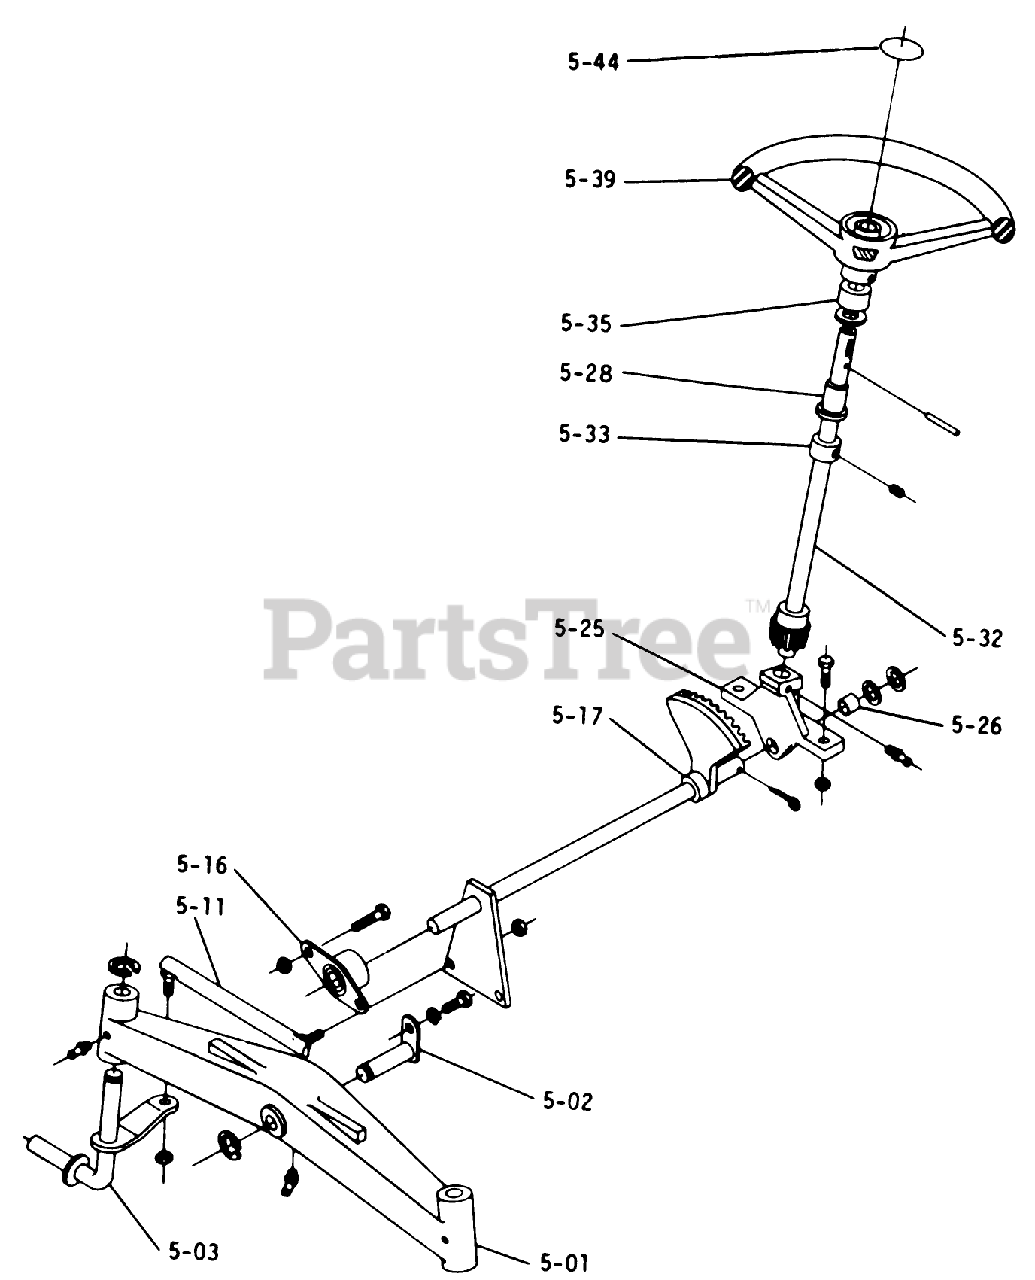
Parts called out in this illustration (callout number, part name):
5-01	FITTING-GREASE
5-02	PIN AND PLATE ASM
5-03	E-RING
5-16	BEARING-FLANGED
5-17	WASHER-SHIM
5-17	WASHER
5-20	WASHER-BOWED
5-26	BEARING-BRONZE
5-28	BEARING
